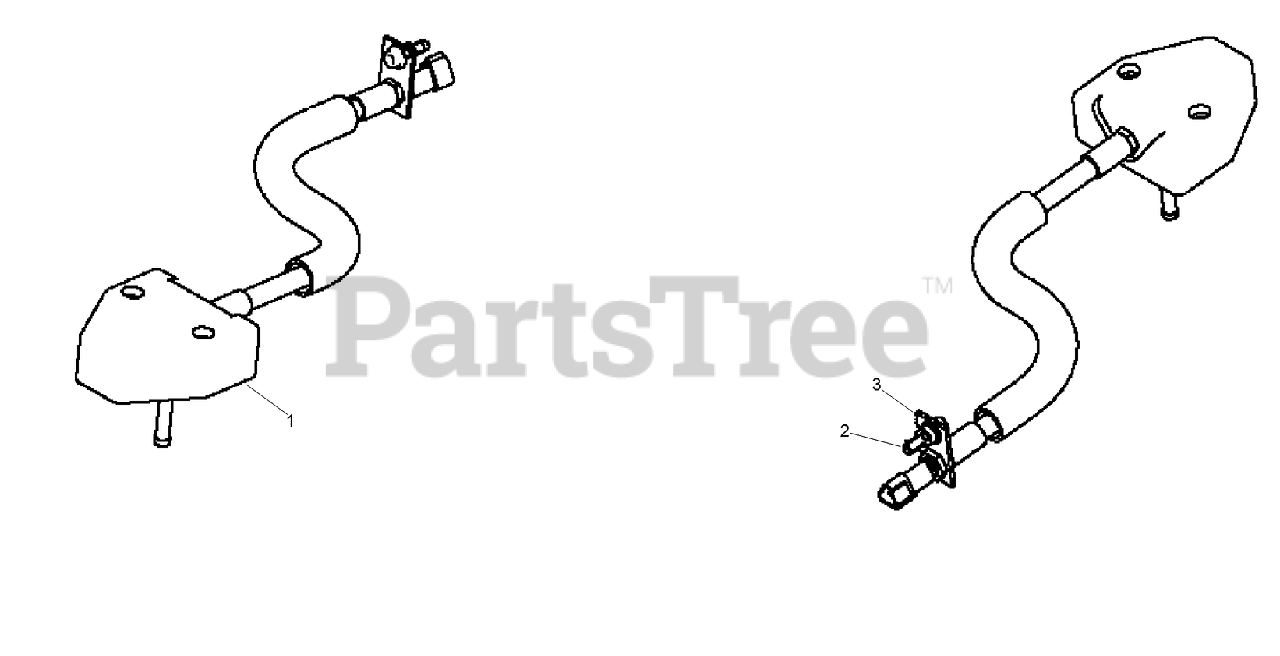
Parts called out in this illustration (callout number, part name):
1	SENSOR-LEAD, STEERING
2	SCREW, METRIC FLANGE FULL - M8 x 25
3	NUT-TORQUE, PREVAILING
